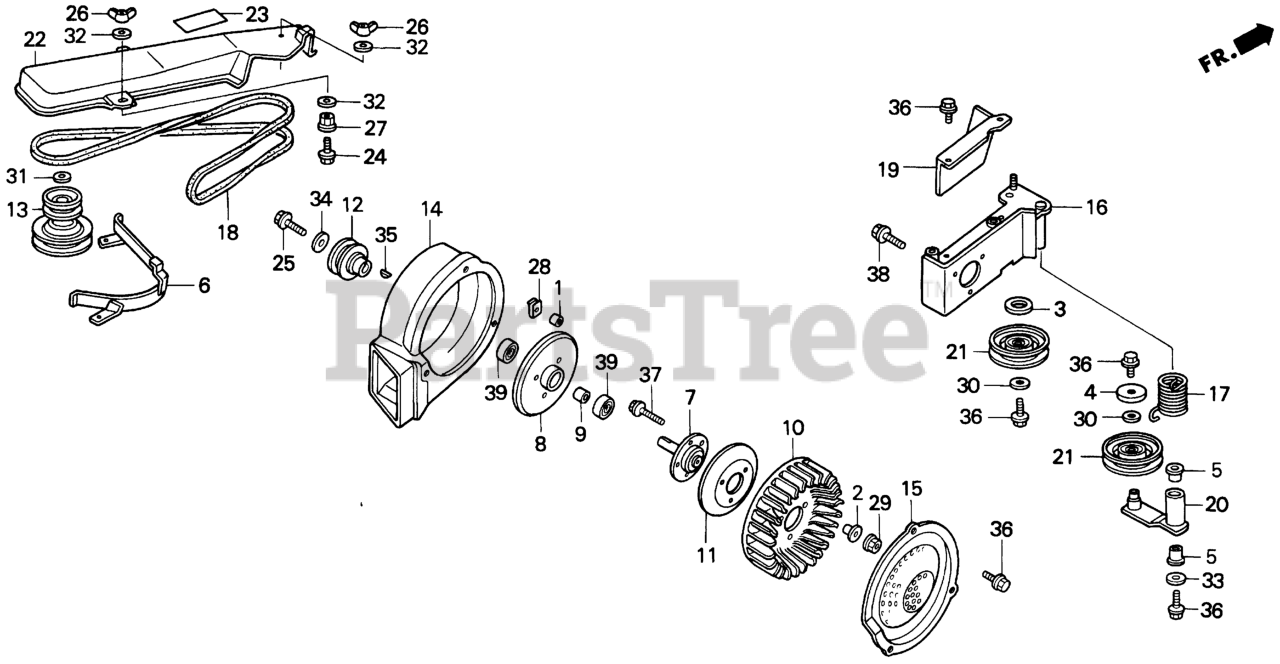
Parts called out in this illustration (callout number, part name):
1	COLLAR, CONTROL
2	COLLAR, TANK SETTING
3	GUARD, TENSION ROLLER
4	GUARD, TENSIONER ROLLER
5	BUSH (15X19X18)
6	STOPPER, BELT
7	SHAFT, BLOWER IMPELLER
8	HOUSING, BLOWER BEARING (NOT AVAILABLE)
9	COLLAR, BLOWER BEARING
10	IMPELLER, BLOWER
11	PLATE, IMPELLER
12	PULLEY, BLOWER
13	PULLEY, BLOWER DRIVE (46")
14	HOUSING, SIDE BLOWER
15	COVER, BLOWER HOUSING
16	BRACKET, SIDE BLOWER MOUNTING
17	SPRING, TENSIONER ARM
18	V-BELT, BLOWER
19	COVER, SIDE BLOWER BELT (A)
20	ARM, TENSIONER
21	PULLEY, IDLER
22	COVER, SIDE BLOWER BELT
23	LABEL, BELT COVER (A)
24	BOLT, FLANGE (0.25 INCH)
25	BOLT, WHEEL RIM
26	WINGNUT (0.25 INCH)
27	NUT, FLANGE (0.25 INCH)
28	NUT, CLIP (6MM)
29	NUT, SELF-LOCK (6MM)
30	WASHER (6X17)
31	WASHER, PLAIN (10MM)
32	WASHER, PLAIN (0.25 INCH)
33	WASHER, PLAIN (6MM)
34	WASHER, PLAIN (8MM)
35	KEY, WOODRUFF (16X12)
36	BOLT, FLANGE (6X12)
37	BOLT, FLANGE (6X22)
38	BOLT, FLANGE (8X16)
39	BEARING, RADIAL BALL (6202UU)
